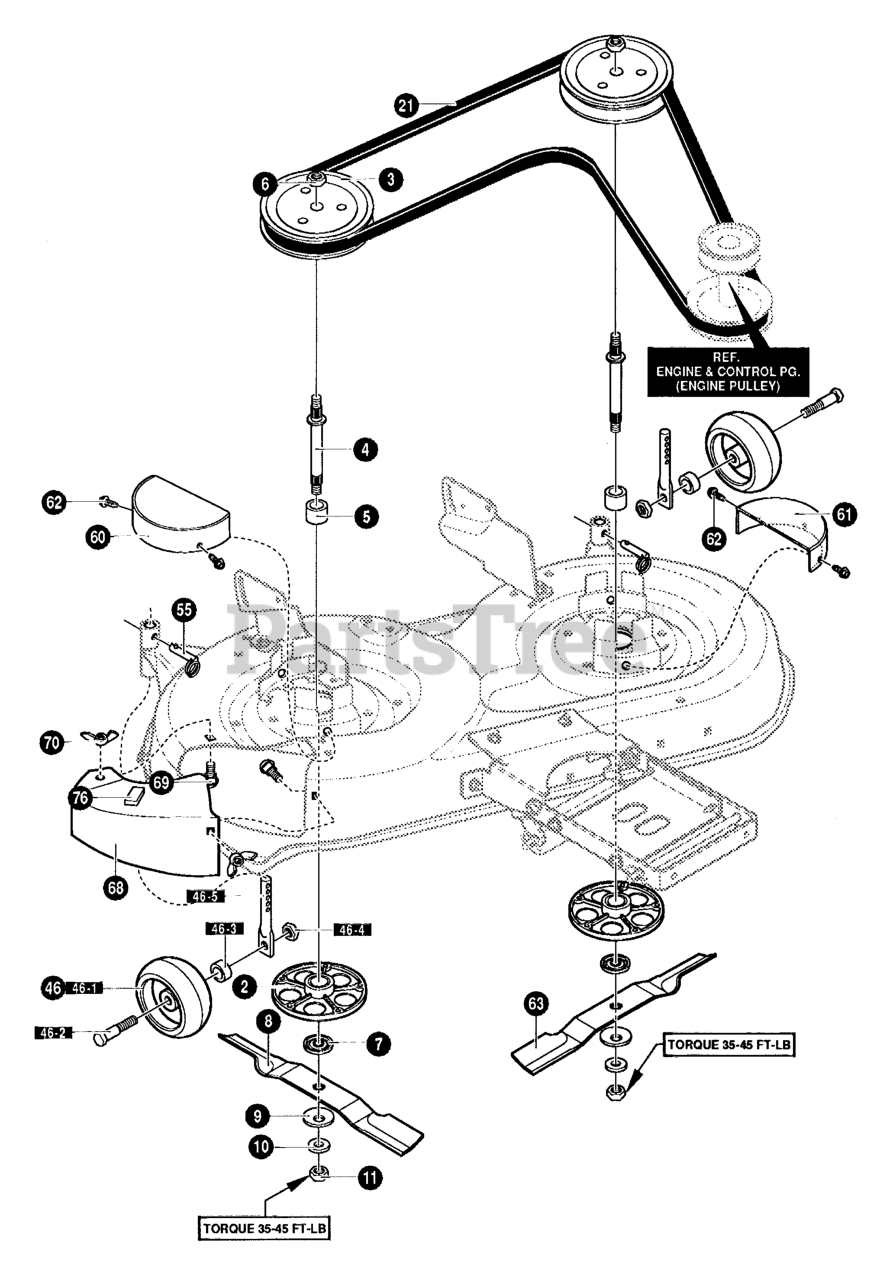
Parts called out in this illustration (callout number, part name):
2	JACKSHAFT HOUSING 42"
3	PULLEY, 42" INPUT
4	JACKSHAFT
5	SPACER
6	NUT, 9/16- 18 UNF- 2B
7	ADAPTER, DECK/BLADE 38"
8	BLADE, 3 N 1 42" RH
9	WASHER, FLAT
10	WASHER, FLAT
11	NUT, 9/16
21	BELT, 42" DECK
46	GAUGE WHEEL, 42"
46-1	WHEEL GAUGE
46-2	BOLT, SHOULDER
46-3	WASHER
46-4	NUT, 3/8- 16
46-5	ROD, GAUGE WHEEL
55	PIN, DETENT RING
60	GUARD, Belt R.H.
61	GUARD, Pulley L.H.
62	SCREW, 1/4-20X.63
63	BLADE, 3 N 1 42" LH
68	COVER, DISCHARGE
69	BOLT, 5/16- 18X .75
70	NUT, WING 5/16- 18
76	ADHESIVE PAD
